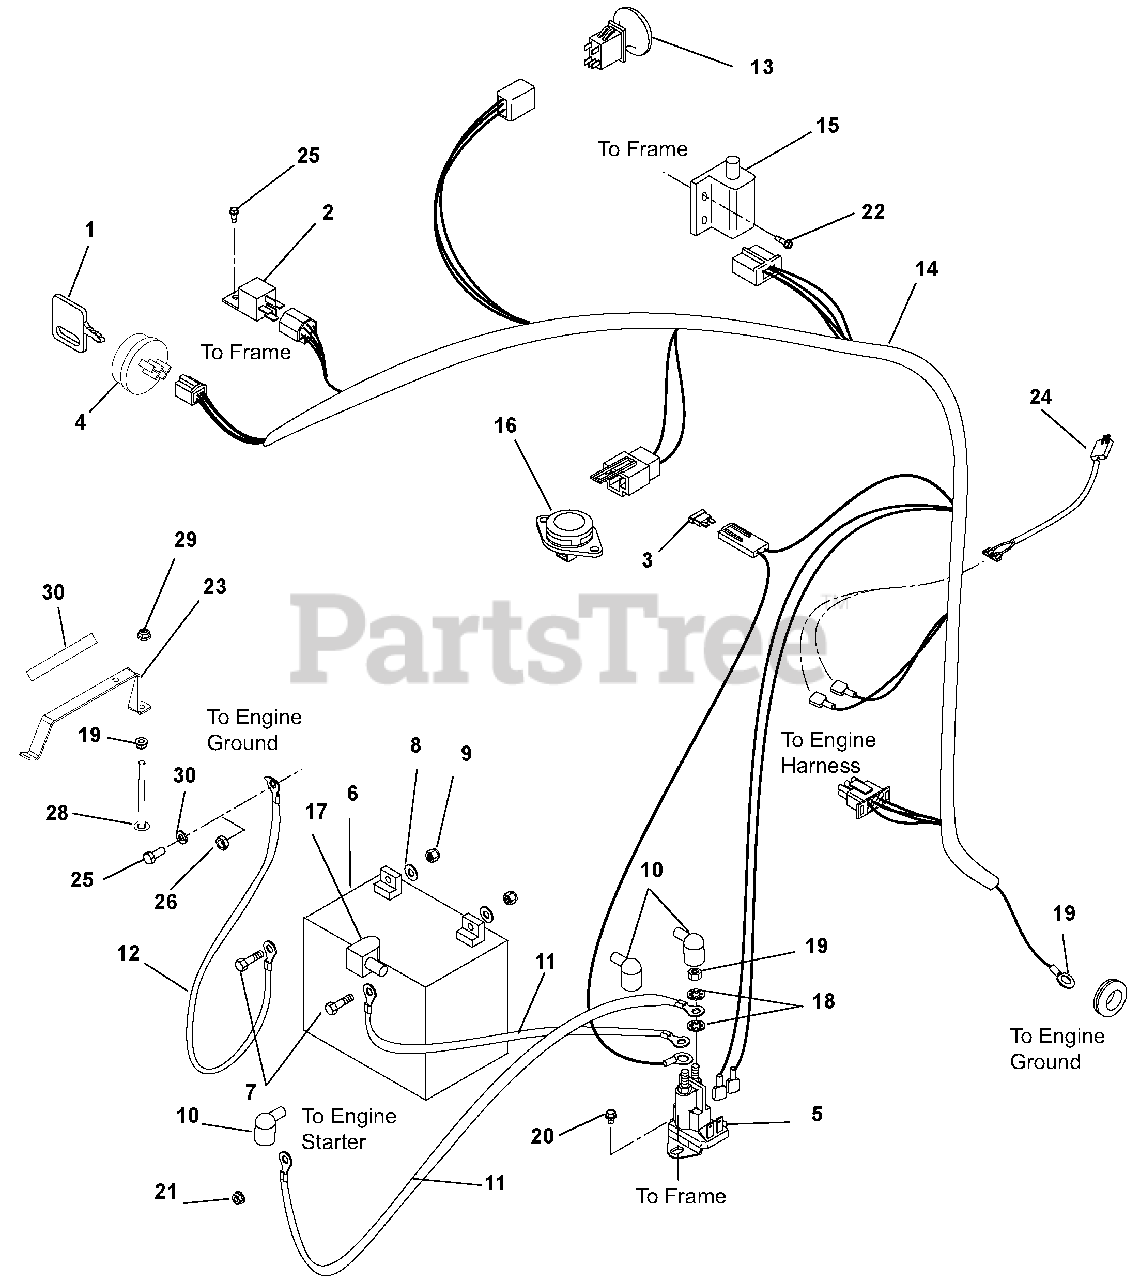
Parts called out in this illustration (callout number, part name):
2	Relay
3	Fuse, 30 AMP
4	KEYSWITCH-IGNITION 3 POS
5	Solenoid
6	Battery, 12V 20 Hour (Can be replaced with U1 190 or larger)
7	Bolt, Hex .25-20 x .75
8	Washer, Flat Steel .281 x .62 x .065
9	Nut, KEPS .250-20
10	Boot, Eyelet Terminal
11	Cable, POS
12	Ground Cable
13	Switch, Clutch With Retainer
14	Harness, Wiring ZT
15	Switch, Double Pole N.O. / N.O.
16	Switch, Snap Mounting (N.O.)
17	Insulator
18	Washer, Locking .31
19	Nut, Jam .31-24
20	Screw, Tapping .250-20 x .37 Hex Washer Head
21	Nut, Locking Top Flange .25-20
22	Screw, 12-14 x .75 HX
23	Hold Down, Battery
24	Harness, Clutch
25	Screw, Tapping 12-24 x .50 Hex Washer Head
26	Nut, Locking Center Jam .375-16 (915146, 168)
27	Wire Clip (915148, 150, 170)
28	Bold, Round Head Square Neck .25-20 x 4.50
29	Nut, Locking Nylon Flange .25-20
30	Decal, U1 Battery Replacement
